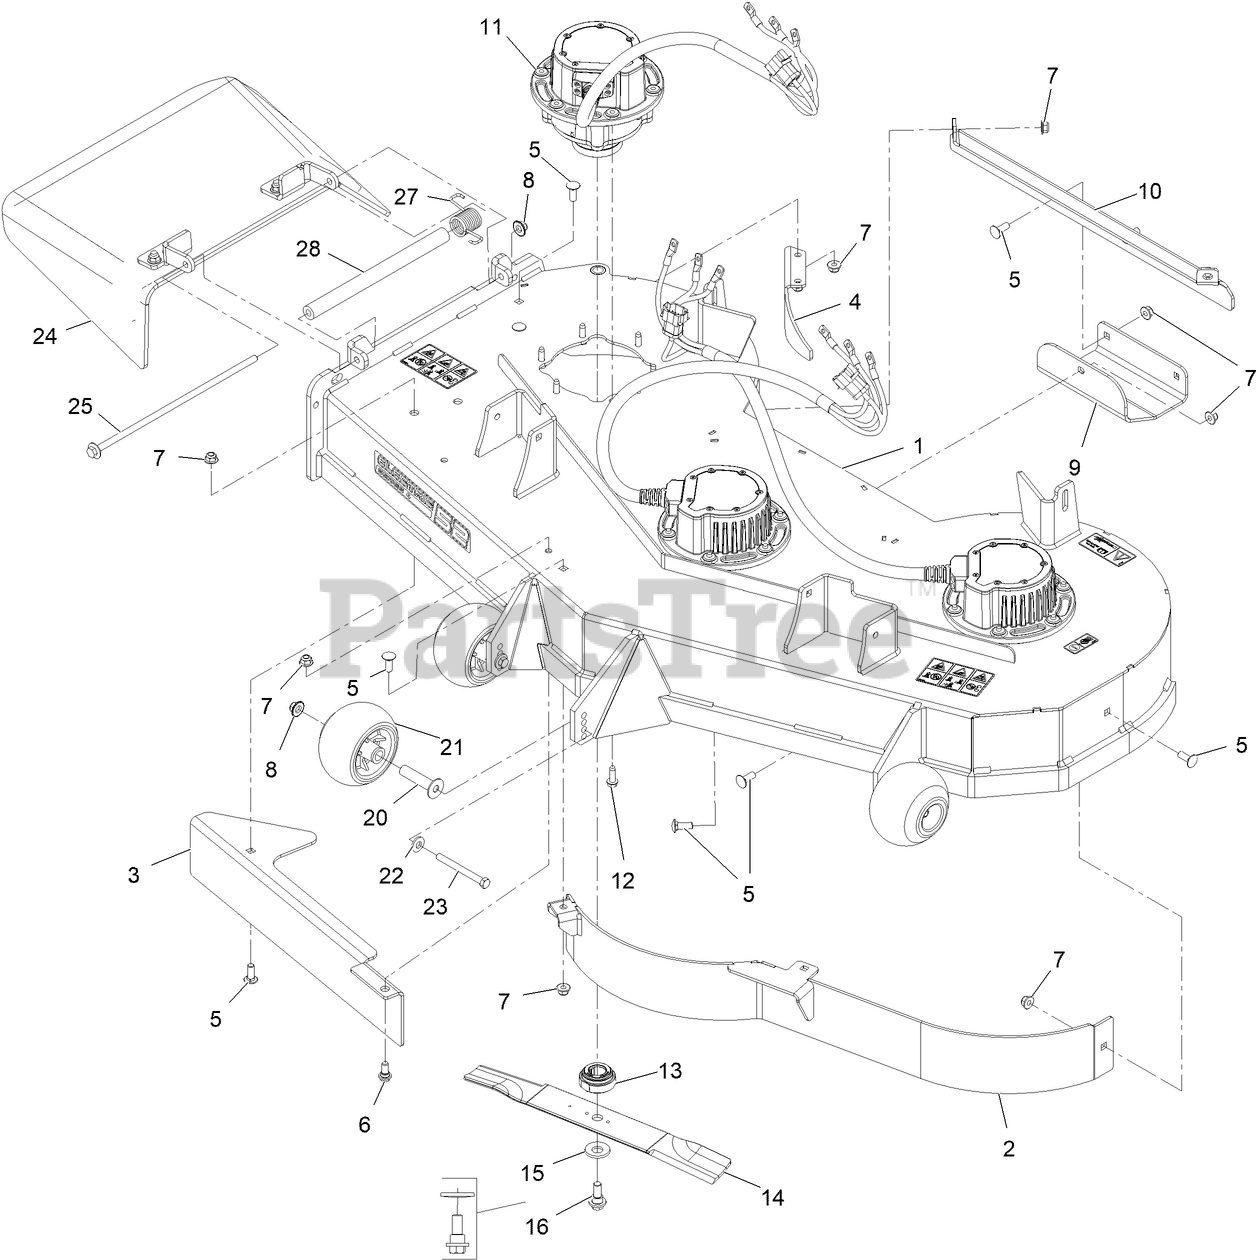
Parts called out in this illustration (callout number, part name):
1	DECK ASM, 52IN
2	BAFFLE ASM, FRONT
3	PLATE-BAFFLE, FORMED
4	BAFFLE-DOGLEG, 52
5	SCREW-CARR
6	BOLT-SHOULDER
7	NUT-HF, NI
8	Nut-Nyloc 3/8-16 Flg
10	BRACKET-SKID
11	MOTOR/GEN
12	SCREW-THD ROLL, HWH
13	RETAINER-BLADE
14	BLADE-18.0IN, MED SAIL
15	Washer-Belleville
16	SCREW-SHOULDER, HWH
20	AXLE, ROLLER
21	ROLLER-SCALP, ANTI
22	WASHER-BELLEVILLE
23	SCREW-HH 3/8-16 X 3 3/4 GR 8
24	ASM, RUBBER DISCHARGE CHUTE
25	Pin, Chute
27	SPRING-TORSION
